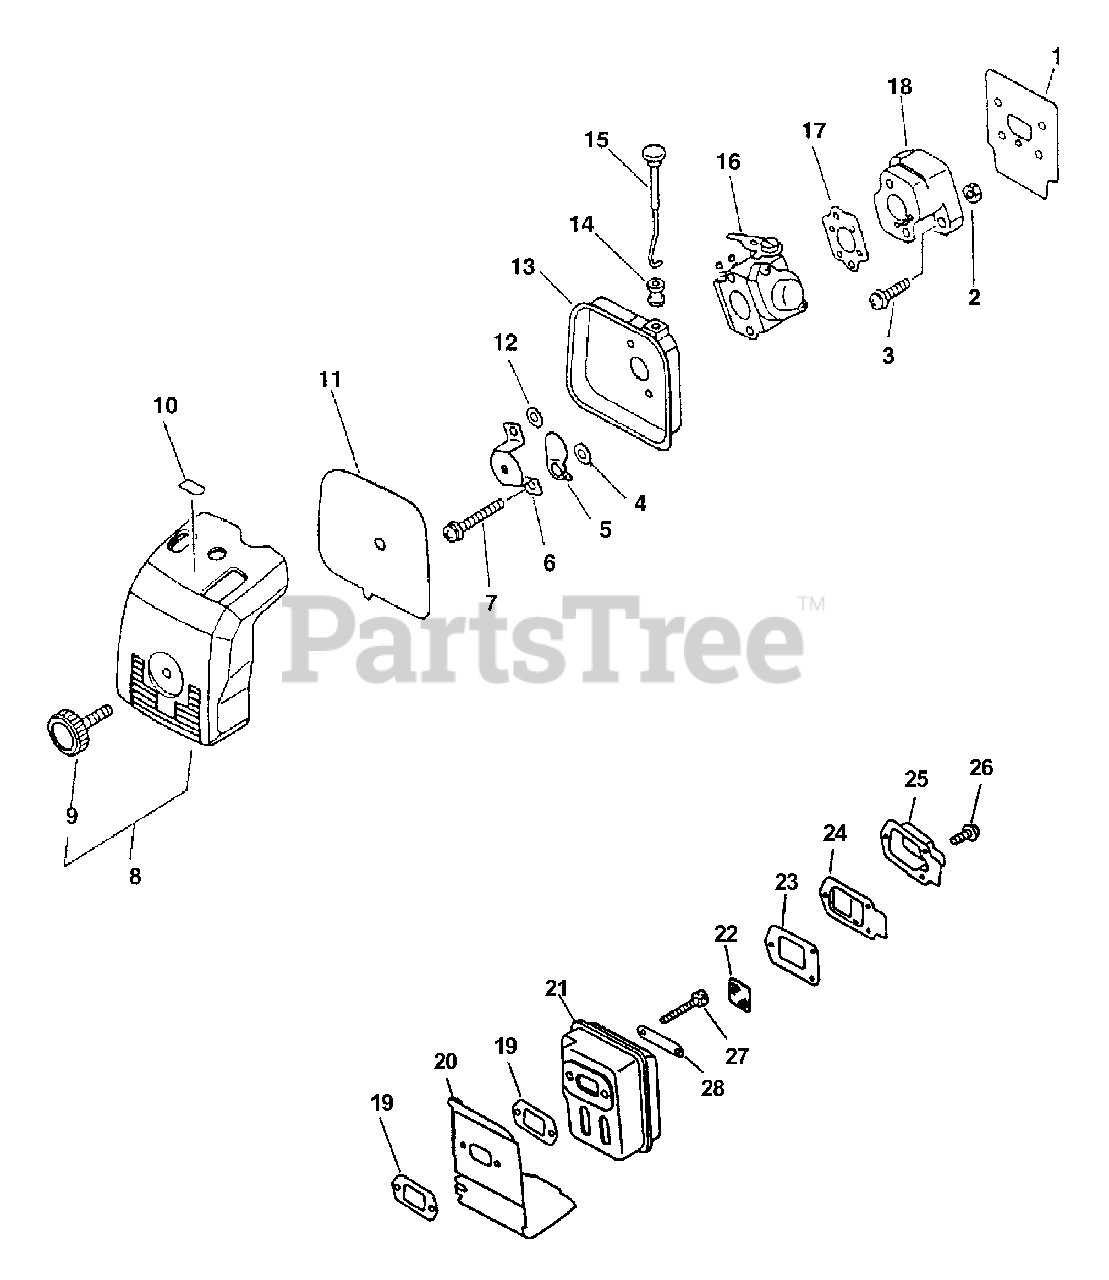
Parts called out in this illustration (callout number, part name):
1	HEAT SHIELD, INTAKE
2	NUT M5
3	SCREW 5×20
4	WASHER 5.2×8×0.8T
5	SHUTTER, CHOKE
6	PLATE, PREVENT
7	SCREW 5×57
8	AIR FILTER COVER ASSY
9	THUMBSCREW
10	LABEL, CHOKE
10	LABEL - CHOKE
11	FILTER, HEAVY-DUTY AIR
12	WASHER, FLAT 5.5×10×0.8
13	CASE, AIR FILTER
14	GROMMET, CHOKE
15	ROD, CHOKE
16	CARBURETOR - WT-424C
17	GASKET, CARBURETOR
18	INSULATOR, INTAKE
19	GASKET, EXHAUST
20	HEAT SHIELD, EXHAUST
22	SCREEN, SPARK ARRESTER
23	GASKET, EXHAUST
24	GUIDE, EXHAUST
25	OUTLET, EXHAUST
26	SCREW 4×10
27	BOLT 5×55
